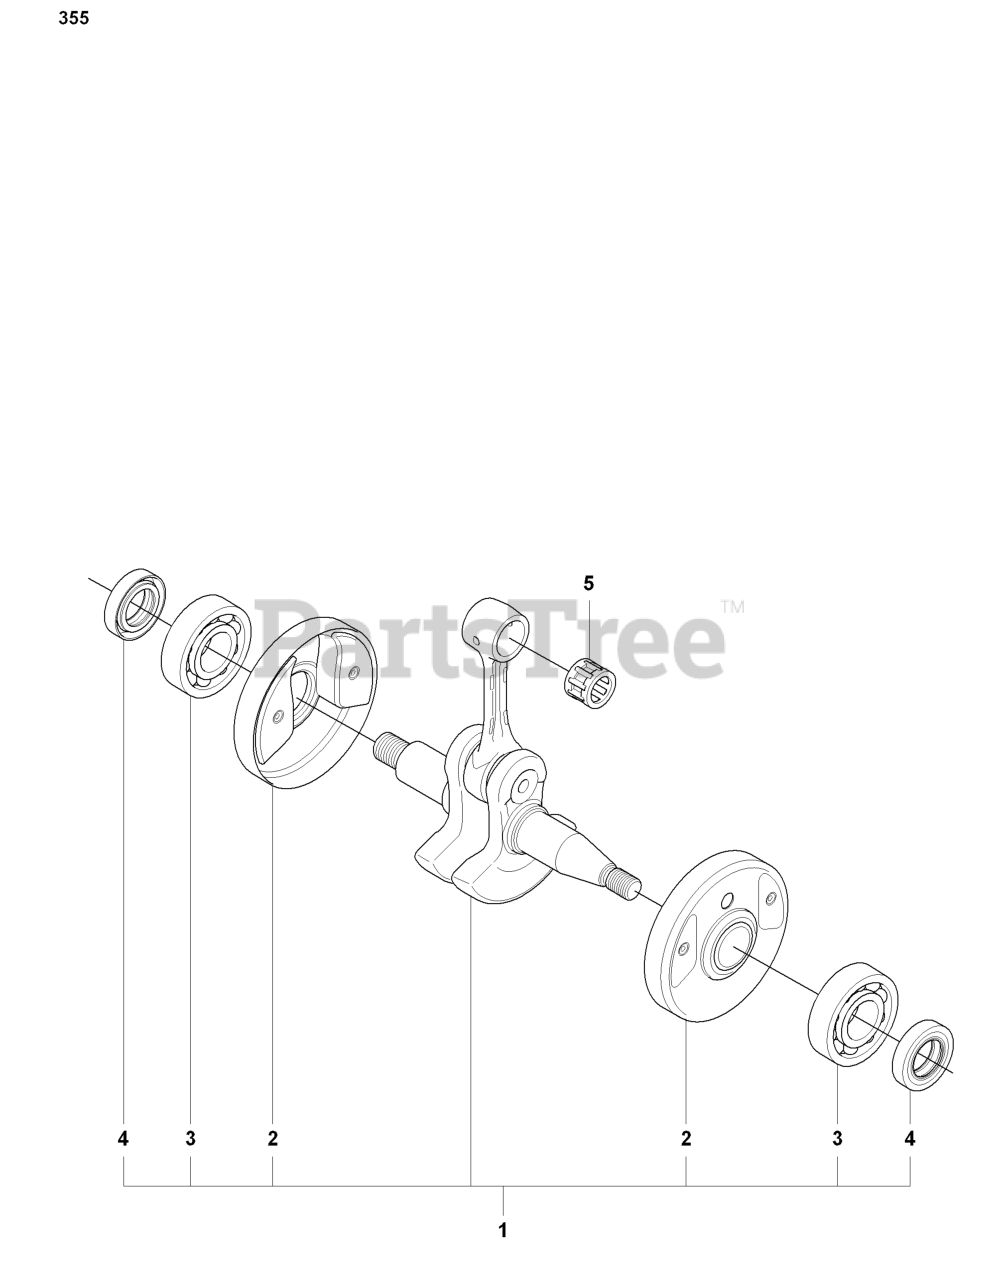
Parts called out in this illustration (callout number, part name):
3	BALL BEARING-6202-C3 SKF
4	SEALING RING
5	SUPPORT BUSHING
